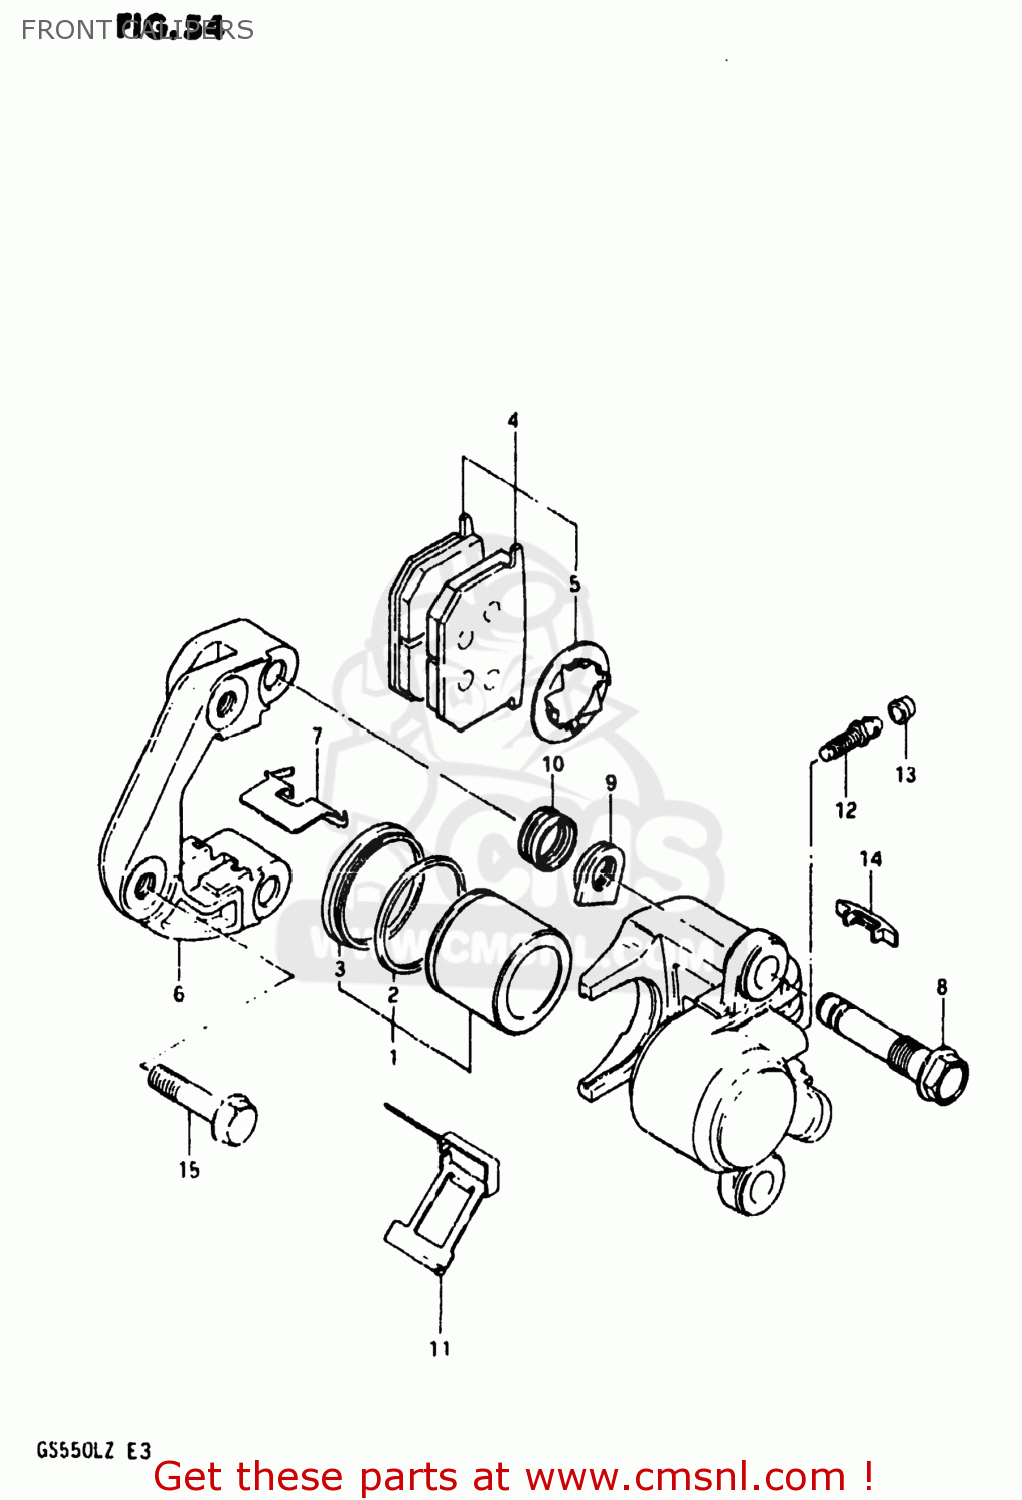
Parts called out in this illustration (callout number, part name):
1	PISTON SET
2	SEAL,PISTON
3	BOOT,PISTON
4	PAD & SHIM SET (MCA)
5	SHIM,PAD
6	HOLDER,CALIPER,LEFT
7	GUIDE,PAD
8	AXLE,CALIPER
9	NUT,CALIPER AXLE
10	BOOT
11	SPRING
12	BREATHER
13	CAP,BLEEDER PL
14	COVER,INDICATOR
15	BOLT
